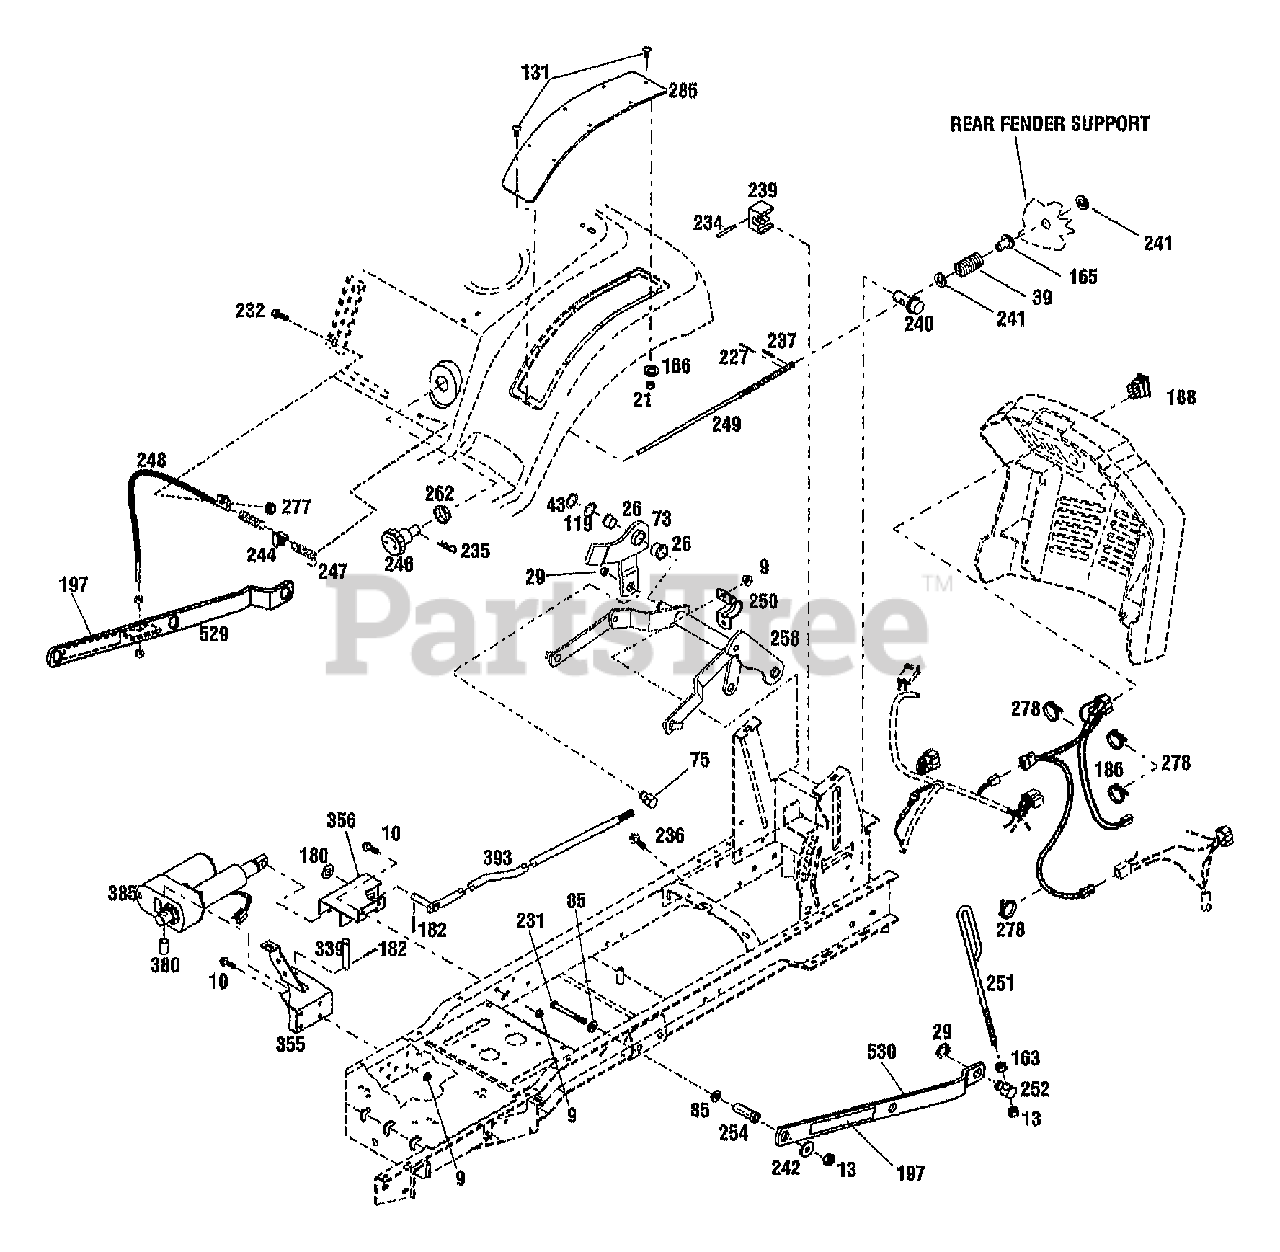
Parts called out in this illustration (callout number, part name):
9	NUT-HFLK 5/16-18 ZP
10	SCR-HHC 5/16-18X.75 GR 5 ZP
13	NUT-LOCK 3/8-16
21	NUT-LK 1/4-20
26	BEARING-FLANGE
29	RING-RETAINING
39	SPRING-COMPRESSION
43	RING-HEAVY EXT HD 1.0 ID
73	ASSM-PIVOT ARM
75	BLOCK-PIVOT
85	WASHER-FLAT 3/8 SAE
119	WASHER-SPEC
131	SCR-MACH .25-20X.62
163	NUT-HEX 3/8-16 ZP
165	BUSHING-.5X.21 NYLON FLNG
166	WASHER-FLAT 1.25X.28X.062 ZP
180	WASHER-1.06X.531X.1 ZP
182	PIN-COTTER .120X1.00 ZP
186	HARNESS-ACTUATOR
188	SWITCH-ROCKER
197	DECAL-WARNING
227	PIN-COTTER .125 X .75 ZP
231	SCR-HH 3/8-16X3.0 G5 ZP
232	SCR 10-24 X 5/8
234	PIN-DRIVE
235	PIN-HITCH
236	SCR-HFLK 5/16-18X.75 ZP
237	PIN-ROLL .156X1.0
239	COLLAR-HEIGHT ADJUST
240	BLOCK-HEIGHT ADJUST
242	WASHER-1.5X.375X.18 ZP
244	INDICATOR-HEIGHT
246	KNOB-HEIGHT ADJUST
247	SPRING-EXTENSION
248	ASSM-CABLE
249	SCR-HEIGHT ADJUST
250	CLAMP-LIFT
252	SWIVEL-REAR LIFT
254	SPACER
262	GROMMET-SNAP BUSHING
277	NUT-KEPS 10-24
278	TIE-CABLE NYLON BLACK
339	PIN-CLEVIS .5X2.75
355	SUPPORT-FRONT
356	SUPPORT-REAR
529	ASSM-LIFT LINK RH
530	ASSM-LT LIFT LINK
